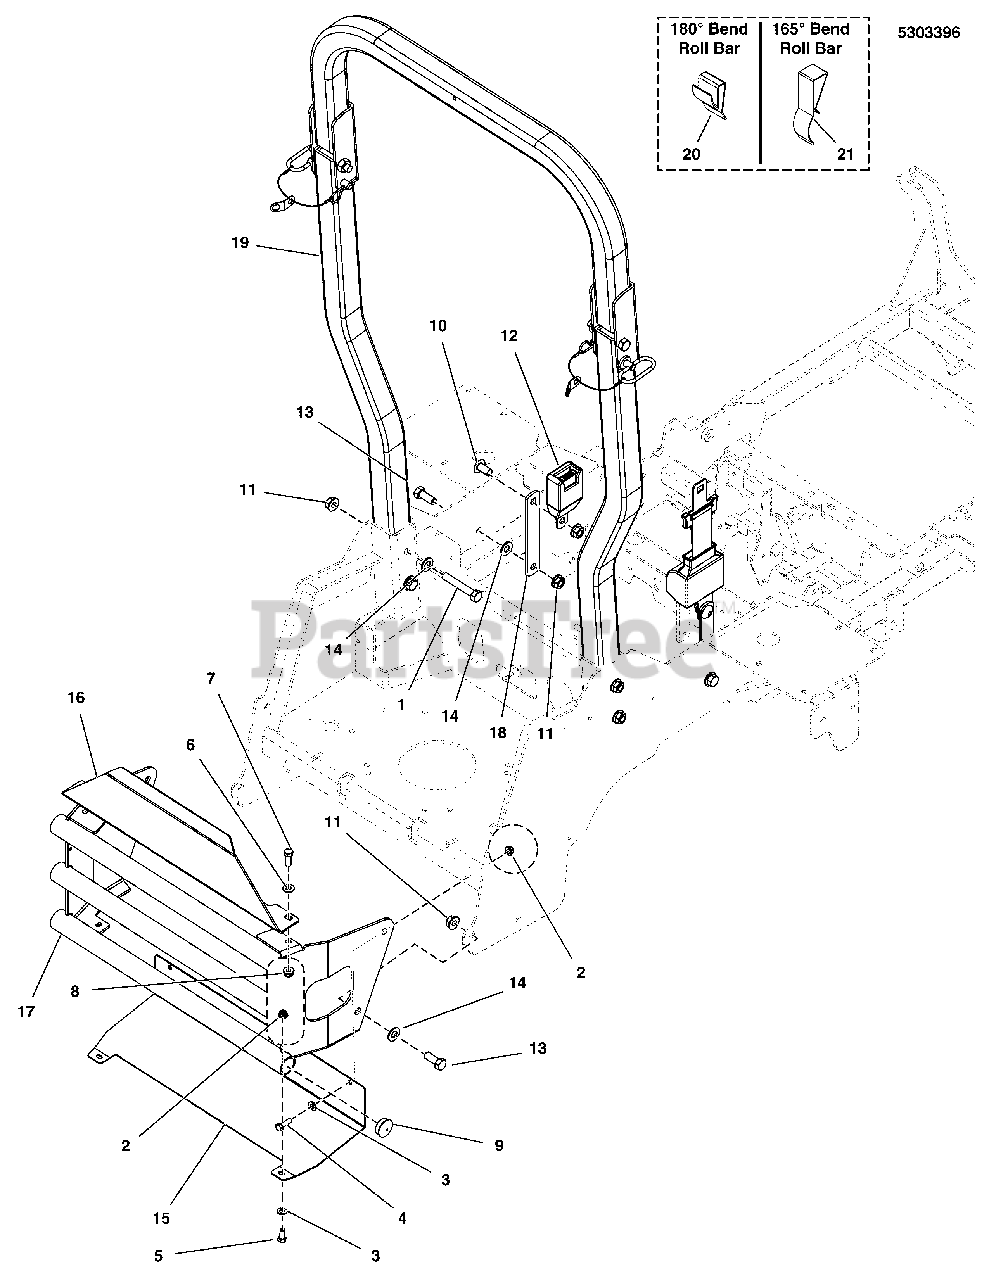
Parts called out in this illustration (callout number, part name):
1	BOLT, 1/2-13 X 3" GD5
2	NUT, 5/16-18 HEX NYLOCK FLANGE
3	WASHER, 5/16 SAE
4	BOLT, 5/16-18 X 1 GD5 YZ
5	BOLT, 5/16-18 X 3/4 GD5
6	WASHER, 3/8 GD.9 FLAT
7	BOLT, 3/8-16 X 1 GD5 YZ
8	NUT, 3/8-16 HEX NYLOCK FLANGE
9	PLUG, PANEL, 1.25 - BLACK
10	SCREW, 1/2-13 X 1.00, SHCS
11	NUT, 1/2-13 HEX NYLOCK FLANGE
12	SEAT BELT, RETRACTING - ASSM
13	BOLT, 1/2-13 X 1-1/4 GD5 YZ
14	WASHER, 1/2 SAE
15	PLATE, HEAT SHIELD, IS700 - BLK
16	PLATE, CARB PROTECTOR - RED
17	WELD, BUMPER - IS700 - RED
18	BAR, MOUNT, SEAT BELT, IS700Z - BLK
19	ROPS (Call 1-800-933-6175 ex.707 for ROPS service)
20	ANTI-RATTLE SPRING, FEMCO #230328972 (SV)
21	ANTI-RATTLE SPRING, ROPS, 165 DEGREE (SV)
